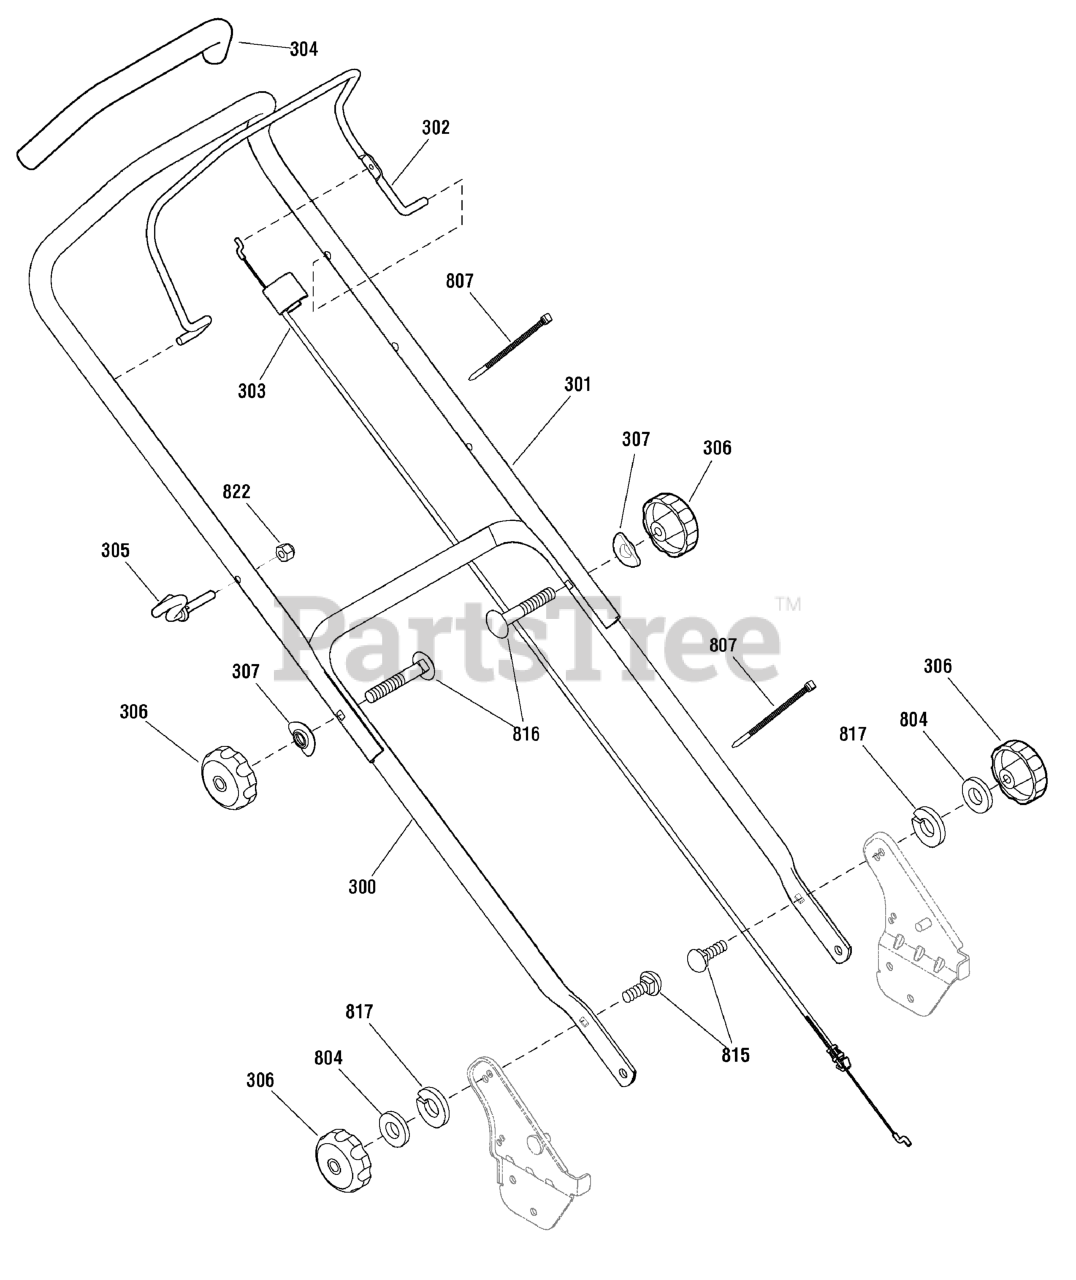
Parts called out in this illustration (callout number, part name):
300	HANDLE, Lower
301	HANDLE, Upper
302	LEVER, Engine Stop
303	CABLE, Engine Stop
304	TUBING, Foam
305	GUIDE, Rope
306	KNOB, 5/16-18
307	WASHER, Formed
804	WASHER, 5/8
807	CABLE TIE
815	BOLT, Carriage, 5/16-18 x 1-1/8
816	BOLT, Carriage, 5/16-18 x 2
817	Washer, Lock
822	NUT, Hex, 1/4-20
